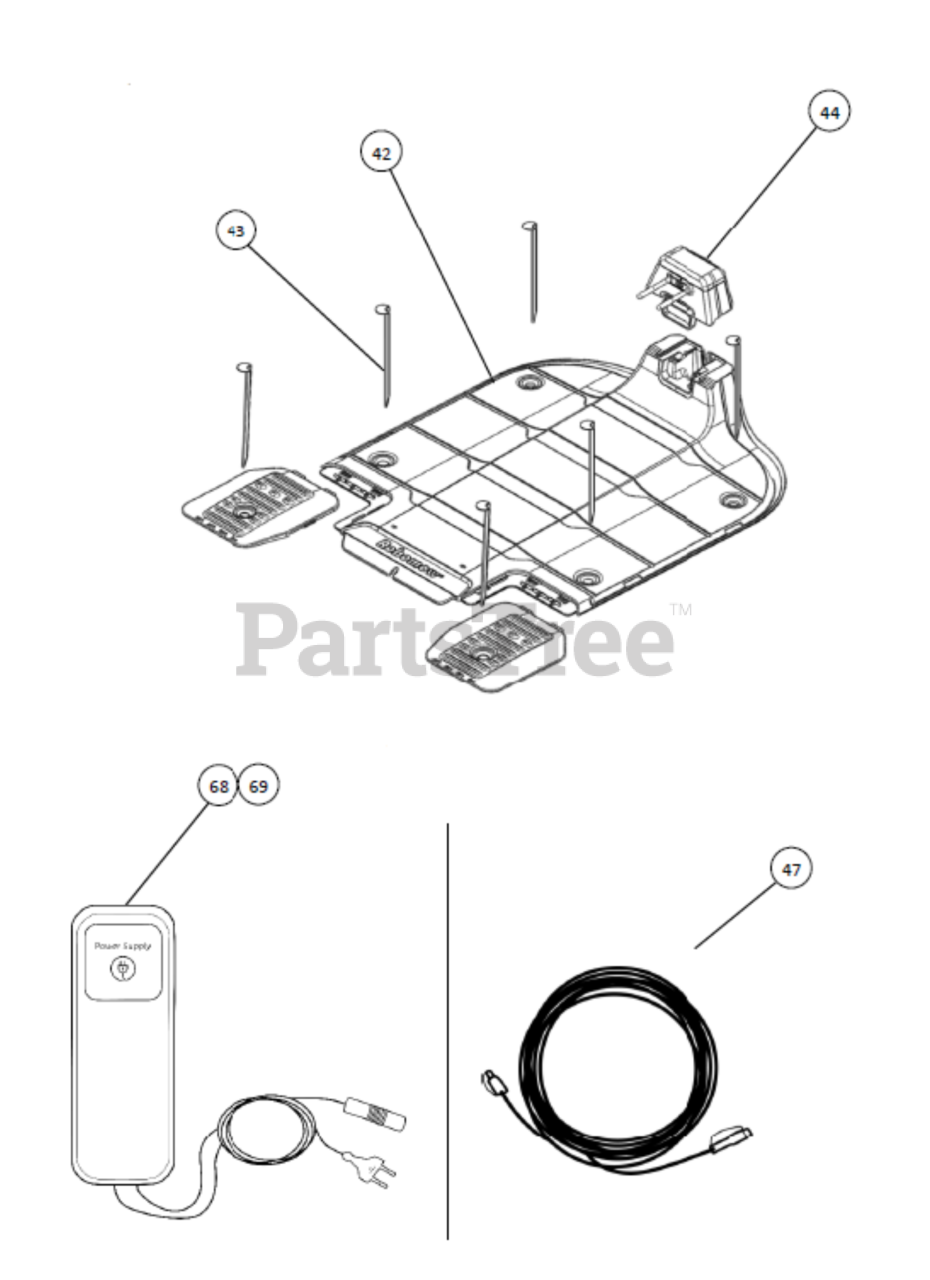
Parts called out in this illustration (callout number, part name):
42	BASE STATION KIT (2019 RS)
42	BASE STATION W/O H
43	FASTENING STAKES-B
44	RS CHARGE ADAPTER (2019)
47	20M CABLE-PBOX TO STATION
68	32V/2A INDOOR SWITCH (IP67)
